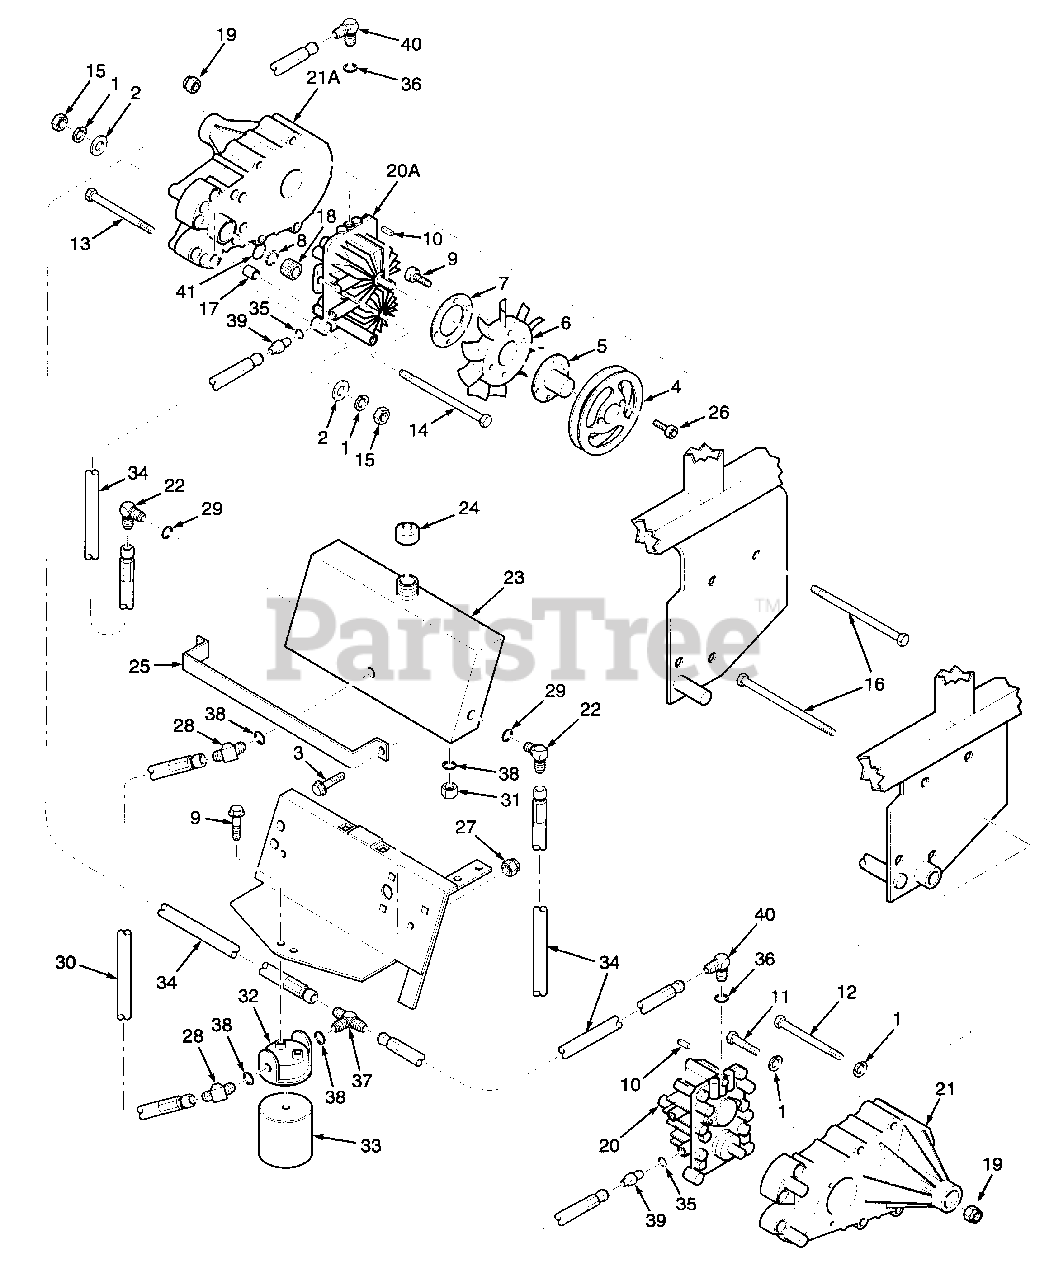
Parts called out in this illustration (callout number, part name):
1	Lockwasher, 5/16"
2	Flatwasher, 5/16" (.344 x .688 x .065)
3	Bolt, Serrated Flange Hex Head 1/4-20 x 3/4"
4	Pump, Pulley
5	Tapered Hub, 15 mm Bore
6	Fan
7	Washer, Back-up
8	Snap Ring
9	Capscrew 1/4-20 x 1/2"
10	Key, 5 mm x 5 mm x 25 mm
11	Bolt, Hex Head 5/16-18 x 1-3/4"
12	Bolt, Hex Head 5/16-18 x 4-1/2"
13	Bolt, Hex Head 5/16-18 x 5"
14	Bolt, Hex Head 5/16-18 x 7-1/2"
15	Nut, Hex 5/16-18
16	Bolt, Hex Head 3/8-16 x 4", grade 8
17	Spacer
18	Gear
19	Nut, Elastic Stop 3/8-16
20	Pump, LH
20A	Pump, RH
21	Axle, LH
21A	Axle, RH
22	Elbow, 90 Degree 9/16-18 JIC to 9/16-18 "O" Ring
23	Oil Tank Reservoir
24	Cap, Oil Reservoir
25	Strap, Oil Reservoir
26	Soc. Head Capscrew, 1/4-20 x 1-1/4"
27	Nut, Elastic Stop 1/4-20
28	Elbow, 45 Degree 3/4-16 JIC to 3/4-16 "O" Ring
29	"O" Ring, 5/64 x 15/32 ID
30	Hose Assembly, Filter Inlet
31	Plug, 3/4-16 "O" Ring
32	Head, Oil Filter
33	Oil Filter, Special
34	Hose Assembly
35	"O" Ring, 3/32 x 3/4 ID
36	"O" Ring, 1/16 x 3/8 ID
37	1/2" T-fitting, 3/4-16 JIC to 3/4-16 "O" Ring
38	"O" Ring, 3/32 x 5/8 ID
39	Tube Union 3/4-16 JIC to 7/8-14 "O" Ring
40	Elbow, 90 Degree 9/16-18 JIC to 7/16-20 "O" Ring
41	"O" Ring
